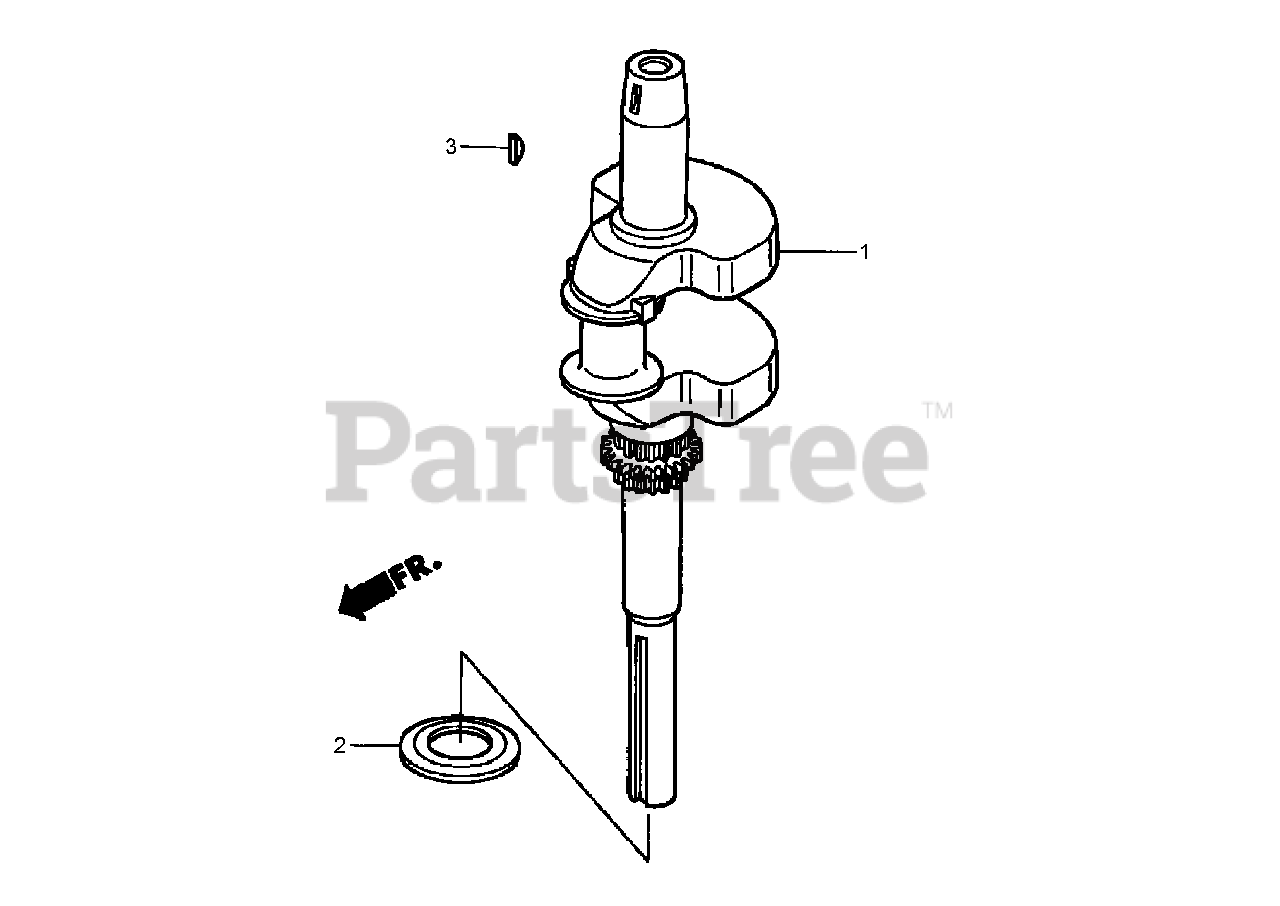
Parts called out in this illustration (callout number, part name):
1	CRANKSHAFT
2	WASHER-THRUST
3	KEY-WOODRUFF, SPECIAL (25X18)
